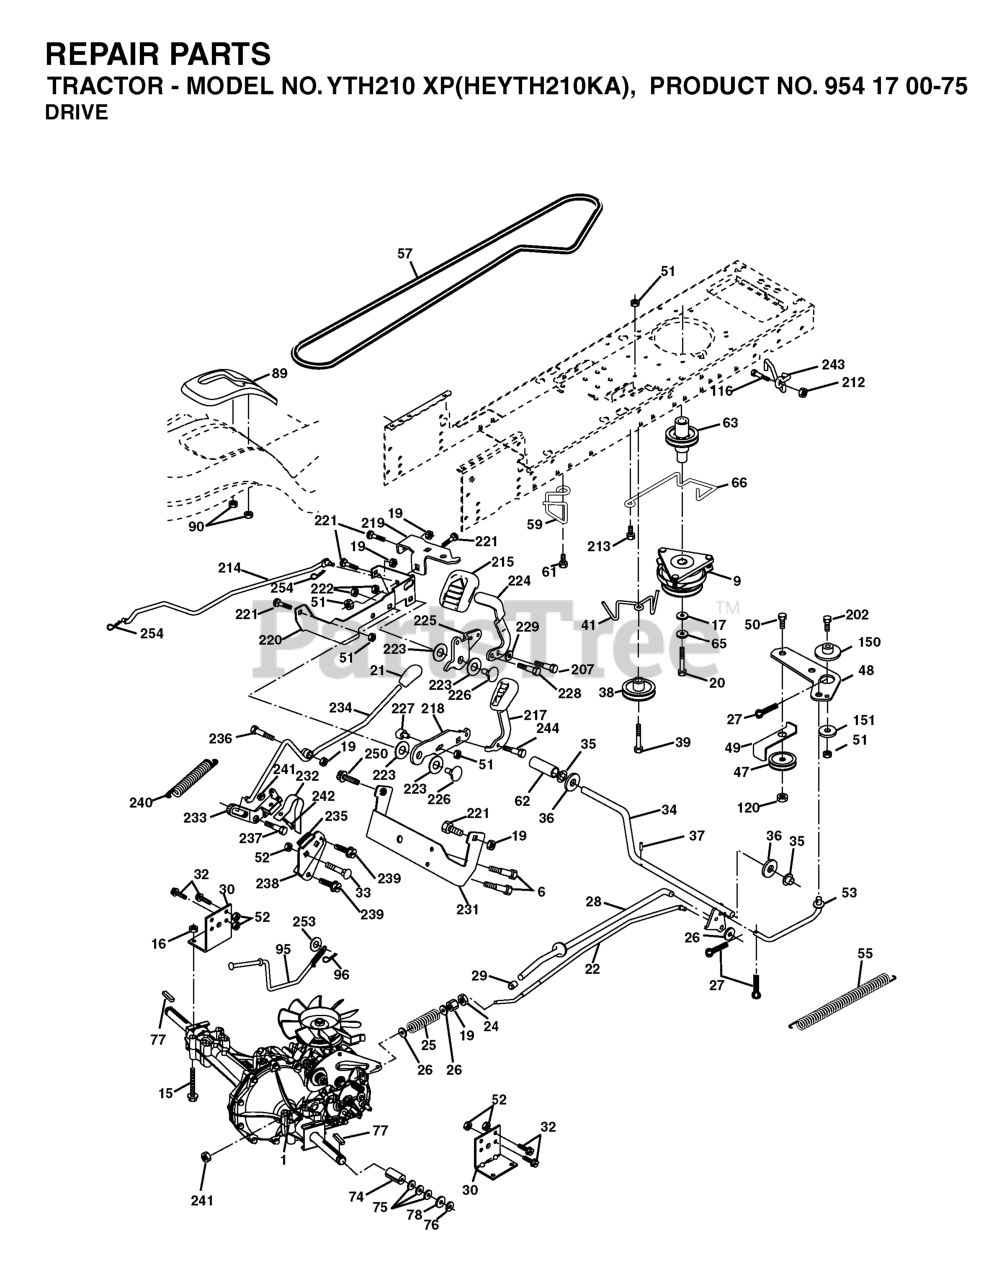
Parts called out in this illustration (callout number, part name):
6	SCREW 5/16"
15	BOLT HEX 5/16-18 GR 5
16	NUT.71038.31-18.HEX.NYLOCK
19	NUT
20	BOLT HEX 7/16-20X4-1/4"
22	ROD.BRAKE.HG-0510.PEDAL.CONTRL
24	NUT
25	SPRING ROD LT
26	WASHER
27	COTTER PIN
28	ROD, PARKING BRAKE
29	PLUNGER CAP
30	BRKT, TRNSXLE MNT 20"
32	BOLT
33	RP BOLT 5/16-18 X3/4 ZN/YEL GR
34	SHAFT, FOOT PEDAL
35	BEARING.NYLON
36	WASHER LT
37	DRIVE PIN
38	PULLEY IDLER COMPOSITE
39	BOLT
41	KEEPER, BELT IDLER
47	IDLER PULLEY
48	BELLCRANK, CLUTCH
49	RETAIN BELT
50	BOLT.3/8-16X1.50
52	LOCKNUT
53	LINK, CLUTCH LT
55	SPRING, RETURN LT
57	DRIVE BELT, LTH & YTH TRACTORS
59	KEEPER, BELT CENTER
61	SCREW 3/8-16X.875
62	COVER, PEDAL (1 2)
63	PULLEY- ENGINE
65	LOCKWASHER
66	KEEPER BELT ENGINE
74	SPACER AXLE
77	SQUARE KEY
89	PAD.FOOTREST
90	NUT.PUSH.3/16
95	ROD BYPASS
96	RETAINER M
116	BOLT D
120	NUT LOCK FLG 3/8-16 UNC
150	SPACER, RETAINER
151	WASHER 12/32X2X10GA
207	SCREW 5/16-18X1
212	NUT
213	SCREW.3/8-16
214	LINK TRANSAXLE
215	COVER PEDAL FORWARD
217	PEDAL REVERSE
218	ARM CONTROL PEDAL REVERSE
219	BRACKET FREST PDL
220	BRACKET MTG.PDL CONTROL
221	Bolt - Rd. Hd. Sq. Neckiage 3/8 16 x 3/4
222	Nut, Crownlock Hex 7/16-14 unc
223	WASHER NYLON
224	PEDAL FORWARD
225	ARM CONTROL PEDAL FORWARD
226	BOLT PIVOT SPACER
227	CAM REVERSE PEDAL LT
228	BOLT SHOULDER
229	WASHER.SERRATED.5/16X.75
231	STRAP TORQUE
232	ACUATOR CRUISE DISENGAGE
233	PAWL CONTROL CRUISE
234	LEVER CONTROL CRUISE
235	SECTOR CONTROL CRUISE
237	SHOULDER BOLT 5/16-18TT
238	ARM MTG.CRUISE SECTOR
239	Screw 5/16-18 x 1/2 Hex, Self Tapping 5/16-18 x 1/2
240	SPRING RETURN CRUISE CONTROL
241	NUT CENTERLOCK
242	BOLT
243	BRKT ASM MTNG
250	SCREW 3/8-16X3/4
254	CLIP RETAINER
